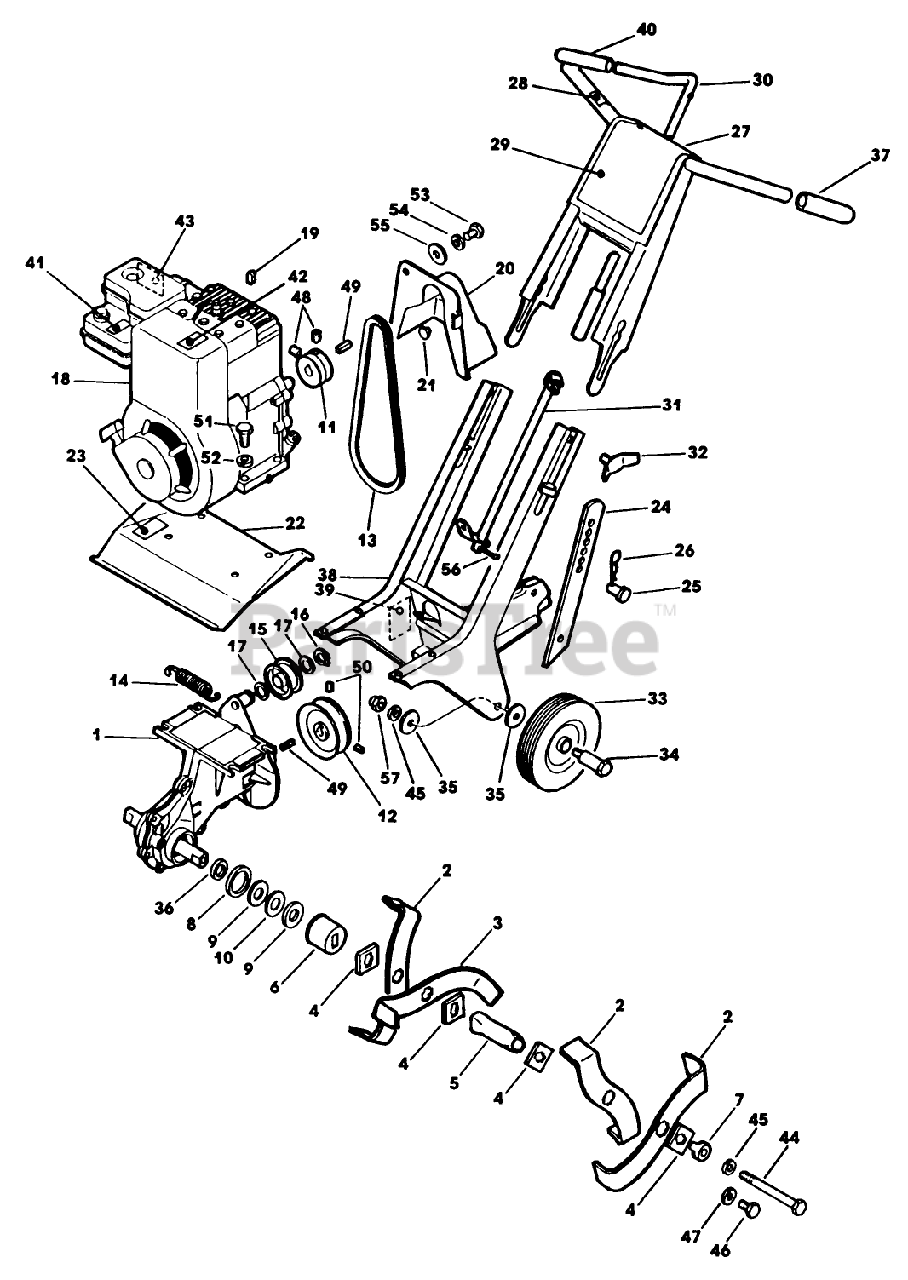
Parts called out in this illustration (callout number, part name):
5	EXTENSION
8	SEAL-FELT
9	SEAL
10	WASHER
13	V-BELT
17	WASHER
26	PIN - SPRING CLIP
36	SEAL
45	WASHER
47	WASHER
50	SET SCREW
57	NUT-LOCKING
